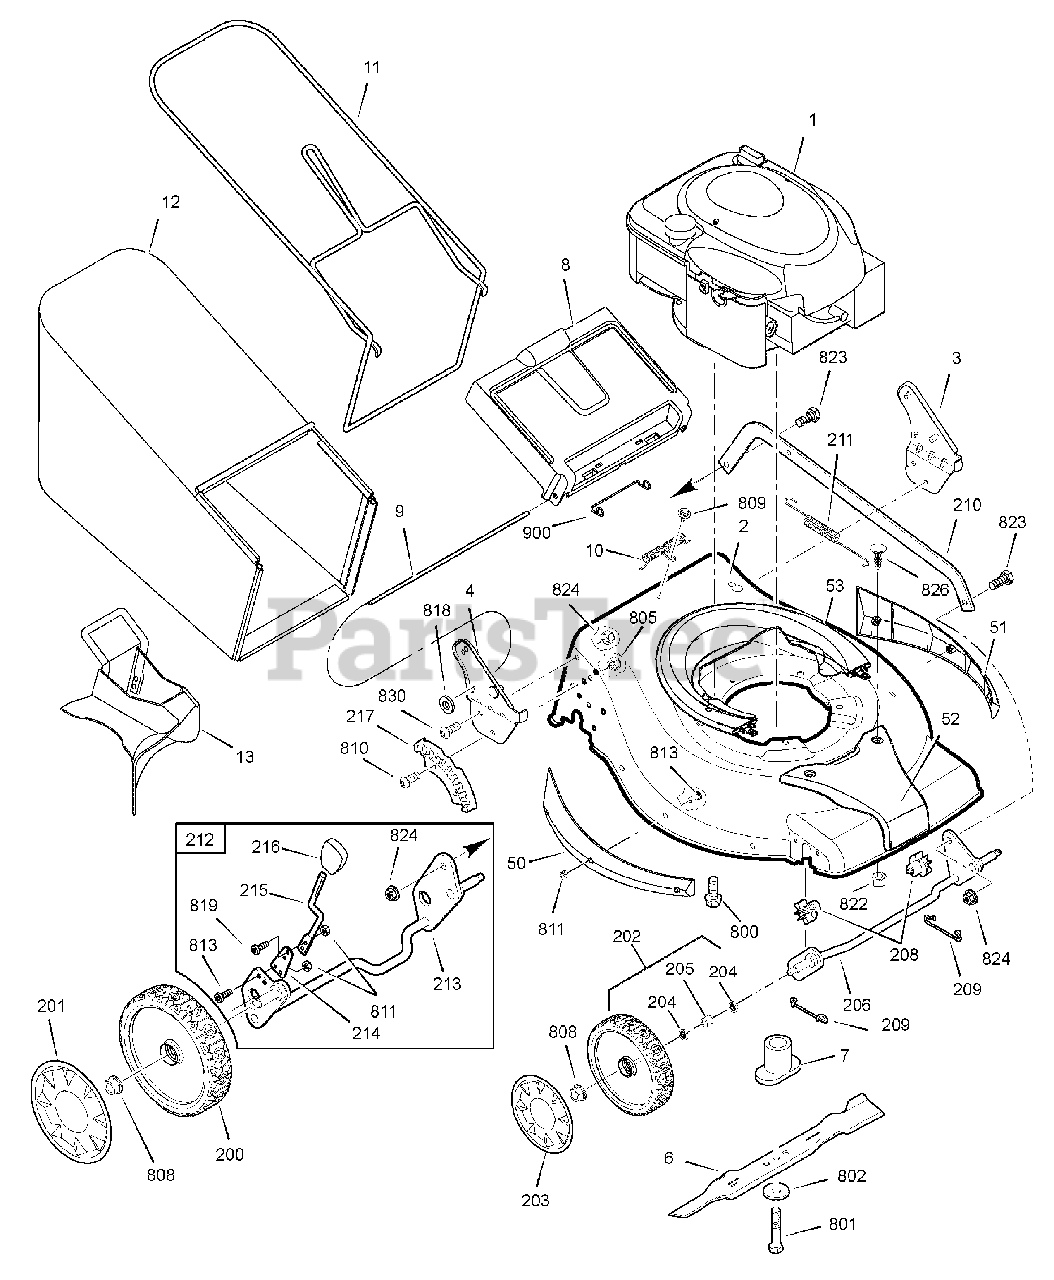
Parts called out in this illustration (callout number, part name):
1	* ENGINE, B&S 700 Series DOV, EU
2	MOWER HOUSING
3	BRACKET ASSEMBLY, Left Handle
4	BRACKET ASSEMBLY, Right Handle
6	BLADE, 19"
7	BLADE ADAPTER ASSEMBLY
8	DOOR, Rear
9	ROD, Rear Door
10	SPRING, Torsion Rear Door
11	FRAME ASSEMBLY
12	BAG ASSEMBLY
13	MULCH PLUG
50	SIDE GUARD, Right
51	SIDE GUARD, Left
52	HOUSING COVER, Front
53	HOUSING COVER, Rear
200	WHEEL, Rear
201	HUBCAP, Rear
202	WHEEL, Front, Complete
203	HUBCAP, Front
204	WHEEL BEARING (Not Available)
205	SPACER (Not Available)
206	CROSSBAR ASSEMBLY, Front
208	BUSHING, Front Crossbar
209	SPRING, Clip Crossbar
210	LINK, Single Lever
211	SPRING, Extension
212	CROSSBAR ASSEMBLY, Rear (Not Available)
213	REAR CROSSBAR
214	SPRING, Adjuster
215	LEVER, Height Adjustment
216	KNOB, Adjuster
217	BRACKET, Height Adjuster
800	SCREW, Hex Head, 3/8-16 x 1
801	BOLT, Blade, 3/8-24 x 2
802	WASHER, Belleville
805	NUT, Nylock, M8 x 1-1/4
808	NUT, Flange, 3/8-16
809	SCREW, Self Tap, #10-16 x 1/2
810	BOLT, Hex Key Head
811	NUT, Nylock
813	SCREW, Torx Head, M5 x .8 x 14mm
818	NUT, Speed
819	SCREW, Torx Head, M5 x .8 x 12.5mm
822	NUT, Hex, 1/4-20
823	BOLT, Shoulder, 5/16-18 x 1
824	Nut, Flange, 5/16-18
826	SCREW, 1/4-20 x 7/8
830	SCREW , 5/16-18 x 3/4
900	SPRING CLIP, Rear Door
1000	DECAL KIT
